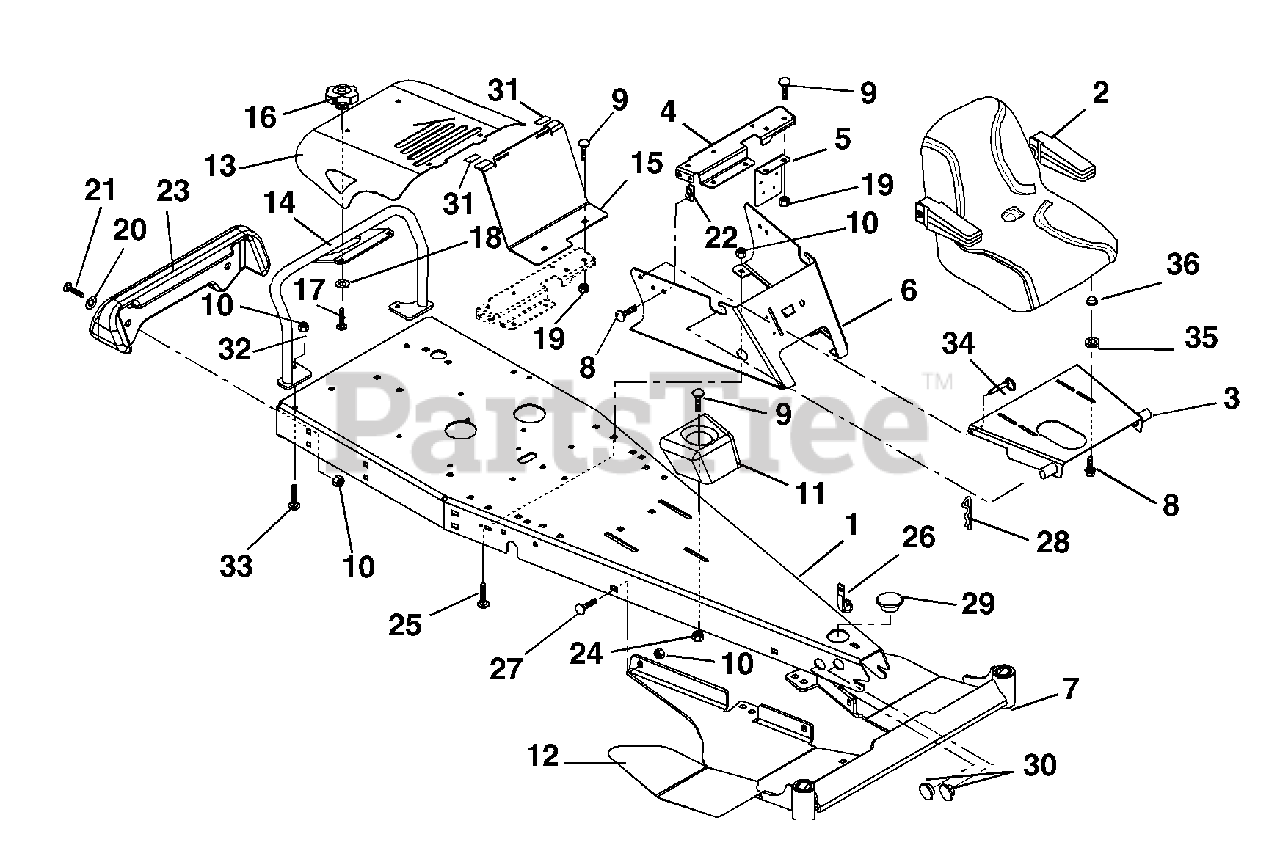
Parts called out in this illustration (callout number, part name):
1	FRAME,RER/SPORT-ZOOM
2	SEAT, TS2500 MICHIGAN W/ARM.
3	WLDM'T, SEAT PLATE
4	REINFORCEMENT, SEAT SUPPORT
5	PANEL-SOLENOID MOUNTING
6	SEAT SUPPORT
7	REST, RER/SZ FOOT
8	BLT-SERHFWH .31-18 X 1 YWZC
9	BLT-RDHDSQNK .31-18X.75 G5BZ
10	NUT-LK-TOP-FLG .38-16 BLKZC
11	CUP HOLDER RER
12	GRIP, LEFT FOOT REST
12	GRIP, RH FOOT REST
13	ENGINE-HOOD ARIENS
14	WLDM'T TUBE
15	BRACKET-HOOD SUPPORT
16	KNOB-CLAMPING, .312-18 NYLOC
17	@BLT-RHDSSQNK .31-18X.75 G5YZ
18	NUT-PUSH .312
19	NUT-LK-TOP-FLG .31-18 BLKZC
20	@WSHR-FL-STL.438X1.00X.083 YWZ
21	@BLT-HEX .38-16X1.75 GR5 YWZC
22	NUT-RTNR .25-20X.56
23	WEIGHT, SPORT-Z
24	@NUT-SPNLK-FLG .312-18 YWZC
25	BLT-RDHDSQNK .38-16X.75 G5BZ
26	J-CLAMP
27	BLT-RDHDSQNK .38-16X1.00 G5BZ
28	PIN-HAIR-EXT .12X.31X2.37 YWZC
29	HOLE PLUG, 1.38
30	HOLE PLUG 1.00"
31	TAPE-FOAM .12X1.00 VINYL
32	RETAINER, .38 PUSH-ON
33	@BLT-RDHDSHSQNK.38-16X1.0 G5YZ
34	PIN-DET W/RING .25X1.00
35	SPACER, .344X1.00X.410
36	NUT-PUSH .312
